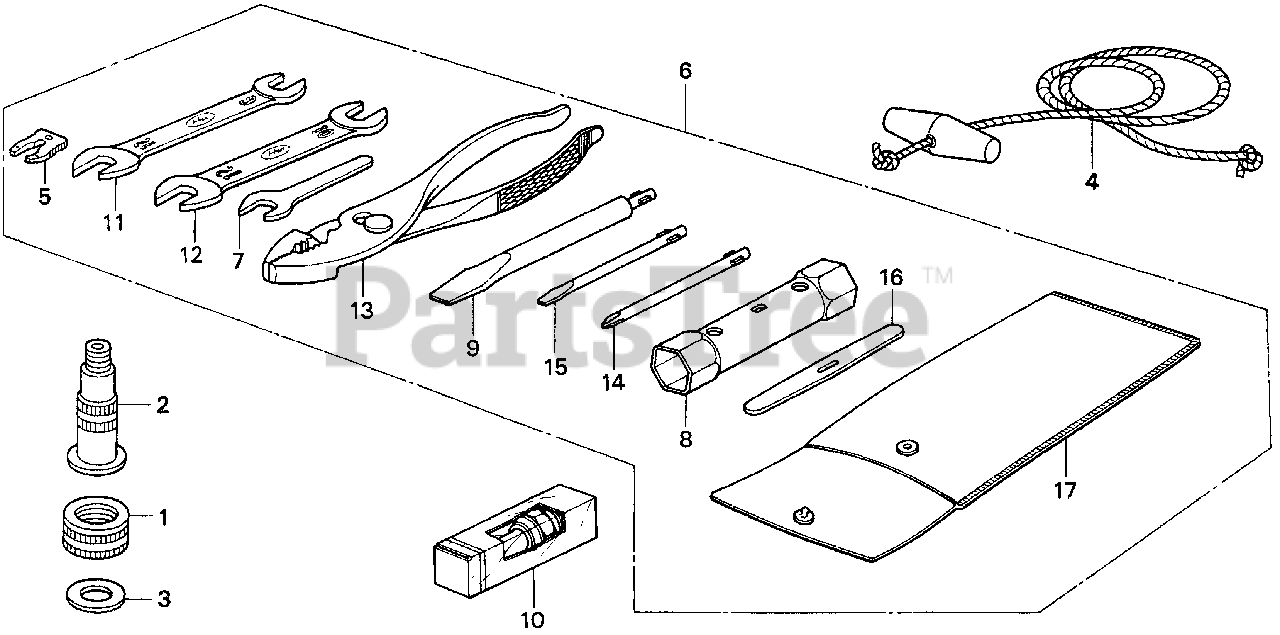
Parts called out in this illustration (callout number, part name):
1	NUT, WATER MOUTH
2	JOINT, WATER HOSE
3	SEAT, WATER MOUTH
4	ROPE, STARTER (#5X55")
5	CLIP, EMERGENCY LOCK
6	TOOL SET (N/A: SEE COMPONENTS)
7	WRENCH (8MM) (OPEN END) (NOT AVAILABLE)
8	WRENCH, BOX (P18X19) (NOT AVAILABLE)
9	SCREWDRIVER, CHECK BOLT
10	SPARK PLUG (DR6HS) (NGK)
10	SPARK PLUG (X20FSR-U) (DENSO)
11	WRENCH (9X12) (OPEN END)
12	WRENCH (10X12) (OPEN END)
13	PLIERS (135MM)
14	SCREWDRIVER 1, PHILLIPS (NO.2)
15	SCREWDRIVER 3, STRAIGHT SLOT (NO.2)
16	LEVER, TIRE
